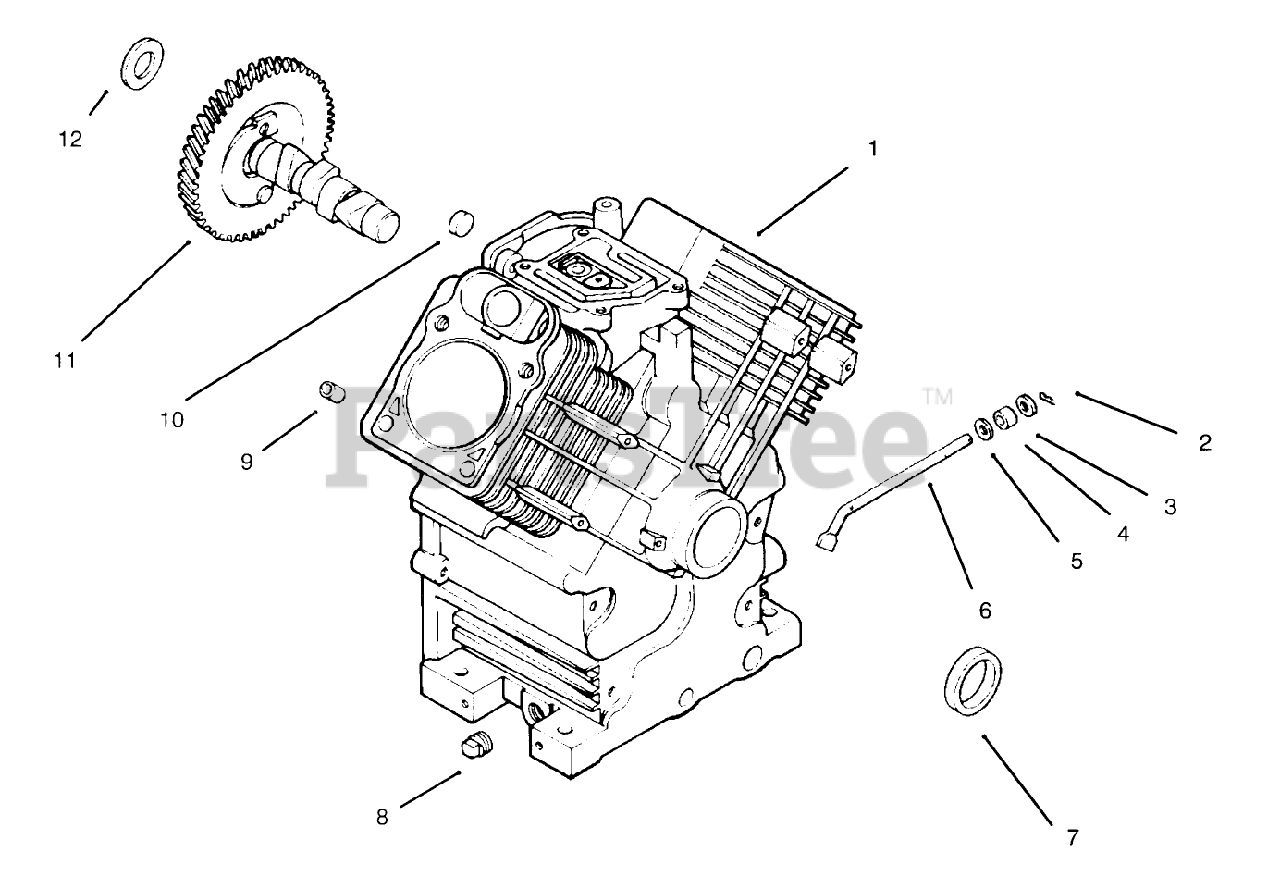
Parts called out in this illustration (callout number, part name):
2	Pin-Hitch
3	Washer
4	Seal-Cross Shaft
5	Washer
6	Shaft-Governor Cross
7	Seal-Oil
8	Plug
9	Pin-Dowel
10	Plug
11	Camshaft
12	Shim-Camshaft
